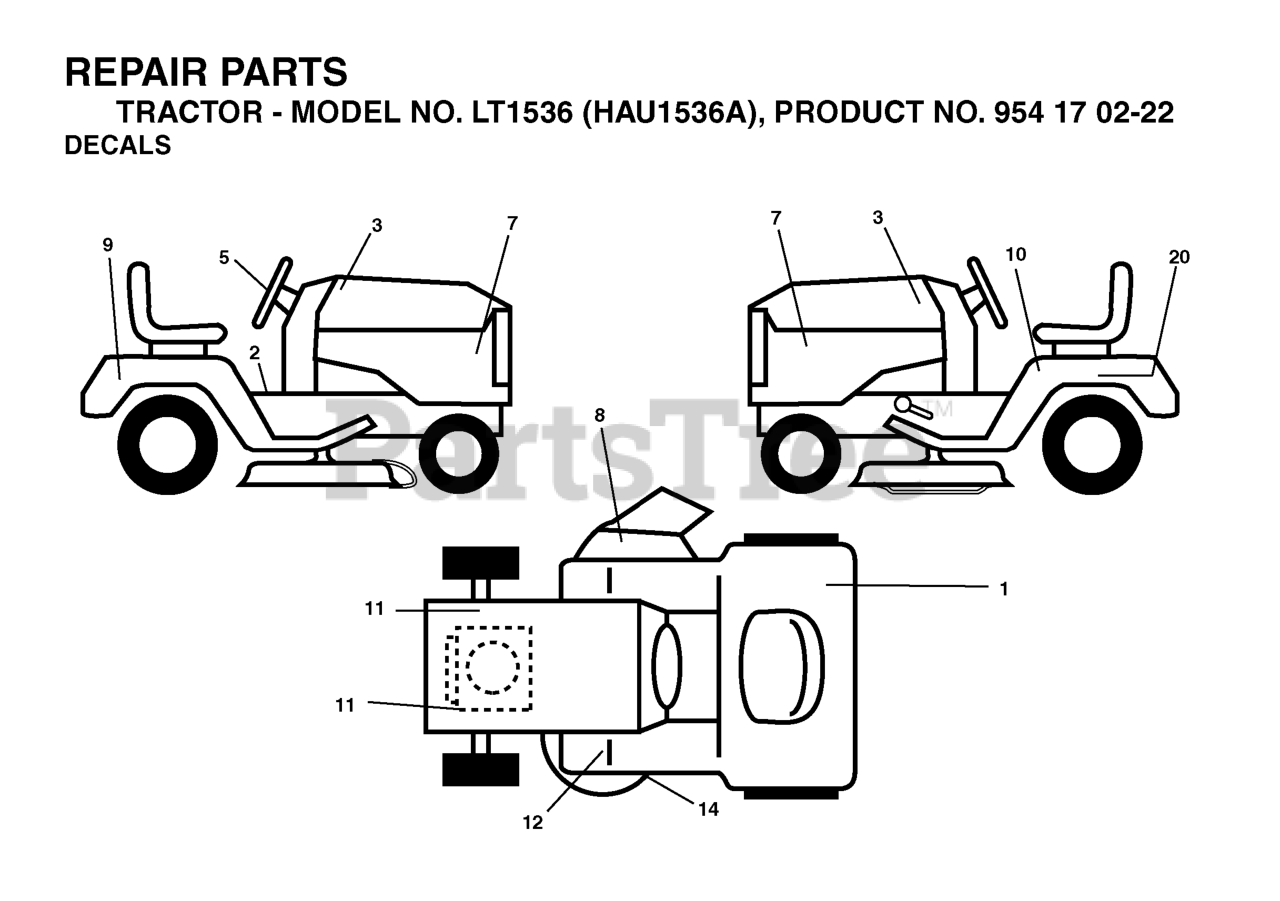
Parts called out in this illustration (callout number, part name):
1	DECAL
2	DECAL PARK BRAKE
5	DECAL.STEERING.HUSQ.BLUE
7	DECAL.HOOD.HUSQVARNA.INTERNATI
8	DECAL.INTERNATIONL.CUTFINGER
10	DECAL READ OWNER'S MAN SYMS
12	DECAL
14	DECAL V-BELT SCHEMATIC
20	DECAL BTRY SYMBOLS
